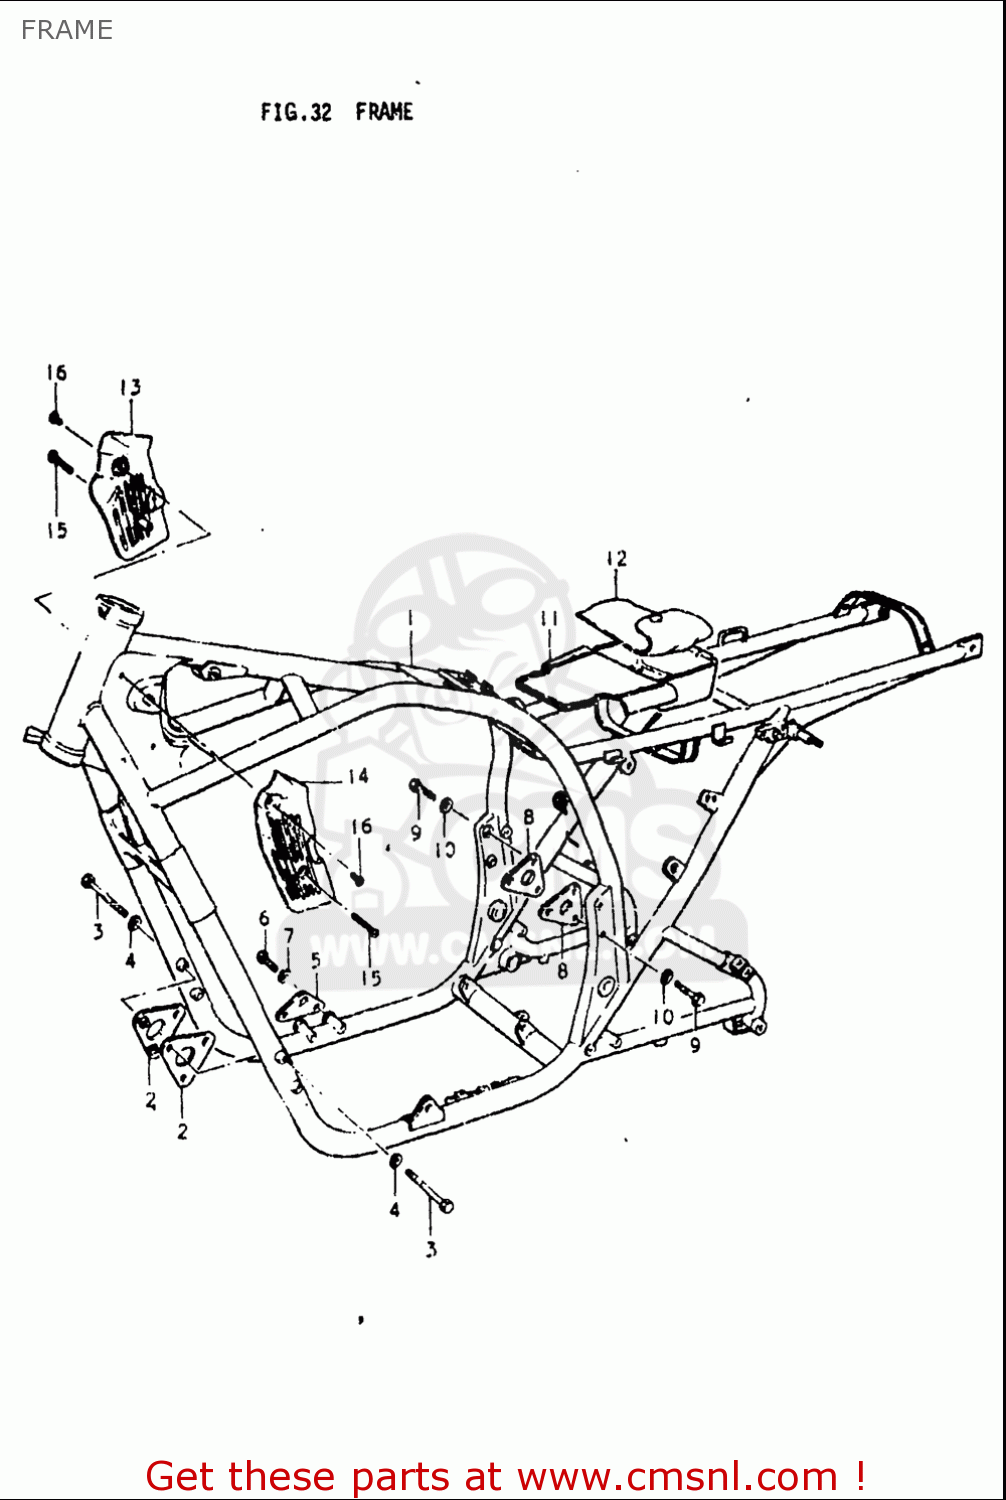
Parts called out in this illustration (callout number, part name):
3	BOLT
4	WASHER,LOCK
5	PLATE,ENGINE MOUNTING
6	BOLT
7	WASHER,LOCK
9	BOLT
10	WASHER,LOCK
12	TOOL ASSY
15	SCREW
16	SCREW
